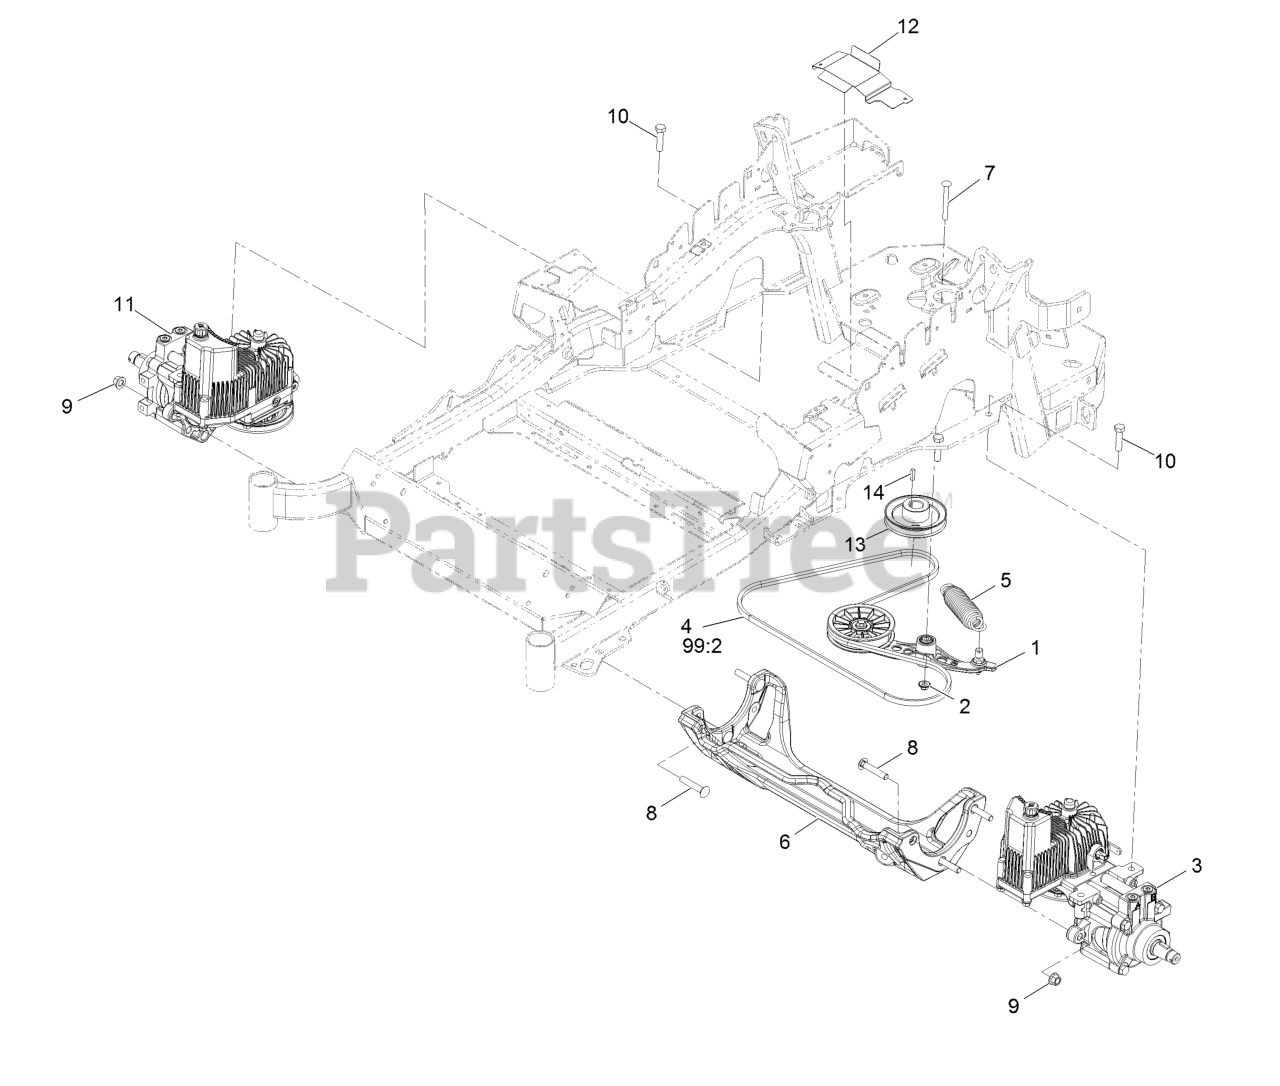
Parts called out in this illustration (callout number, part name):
1	Pump Idler ASM
2	Nut-Nyloc 3/8-16 Flg
3	LH Hydro ASM (12Cc No Fan)
4	Belt-V
5	Spring-Extension
6	Cradle-Hydro
7	Bolt-Carriage Shoulder 3/8-16 X 3 1/2
8	Screw-CARR
9	Nut-Lock 1/2-13
10	Screw-HH 1/2-13 X 1 1/4
11	RH Hydro ASM (12Cc No Fan)
12	Guard-Belt
13	Sheave-Pump, Drive
14	Key-Machine 1/4 X 1/4 X 1
99	Bottle-Oil, 32Oz Hydraulic
99	Filter-Hydro
99	Bottle,Oil 1 Gallon Hydraulic
99	Kit,Hydro Service
99:1	Bottle-Oil, 32Oz Hydraulic
99:2	Belt-V
99:3	Filter-Hydro
